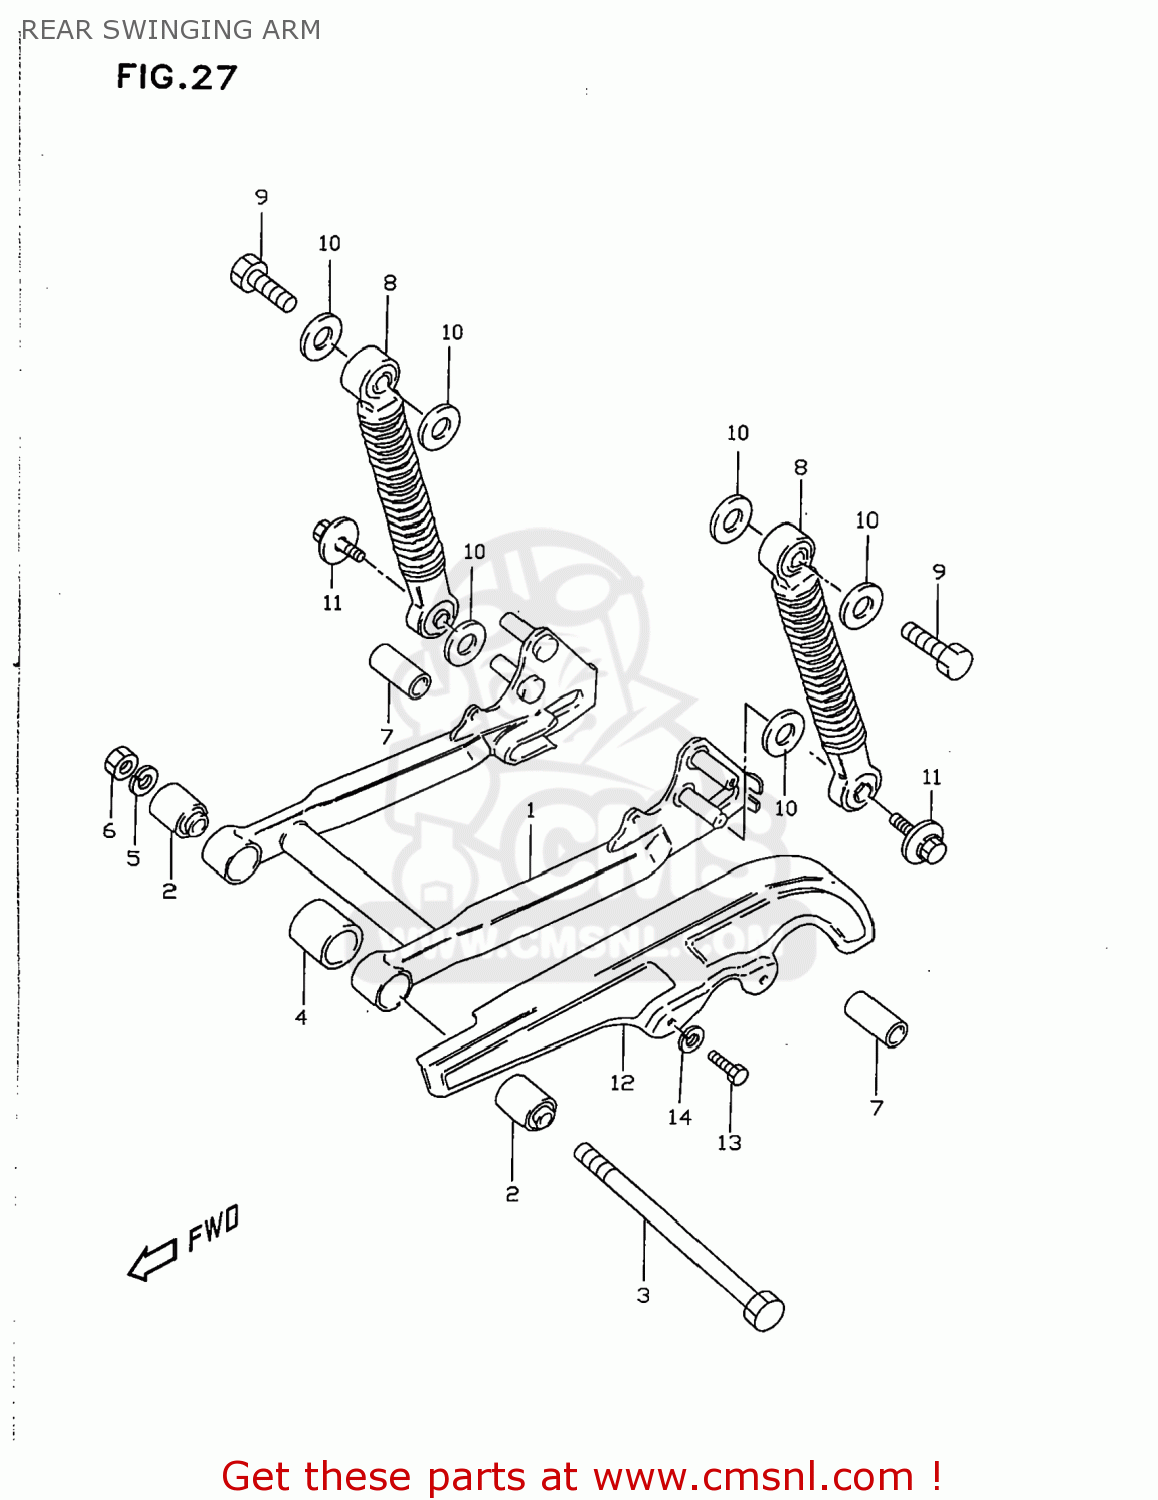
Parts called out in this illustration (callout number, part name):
1	SWINGINGARM ASSY,RR
2	BUSH
3	SHAFT,RR SWINGINGARM PIVOT
4	CUSHION
5	WASHER(10.5X22X1.6)
6	NUT
7	CAP,RR SHOCK ABSORBER BOSS
8	ABSORBER ASSY,RR SHOCK
9	BOLT,M10X1.25X
10	WASHER(10.5X22X1.6)
11	BOLT(6X12)
12	CASE,CHAIN
13	BOLT
14	LOCK WASHER
